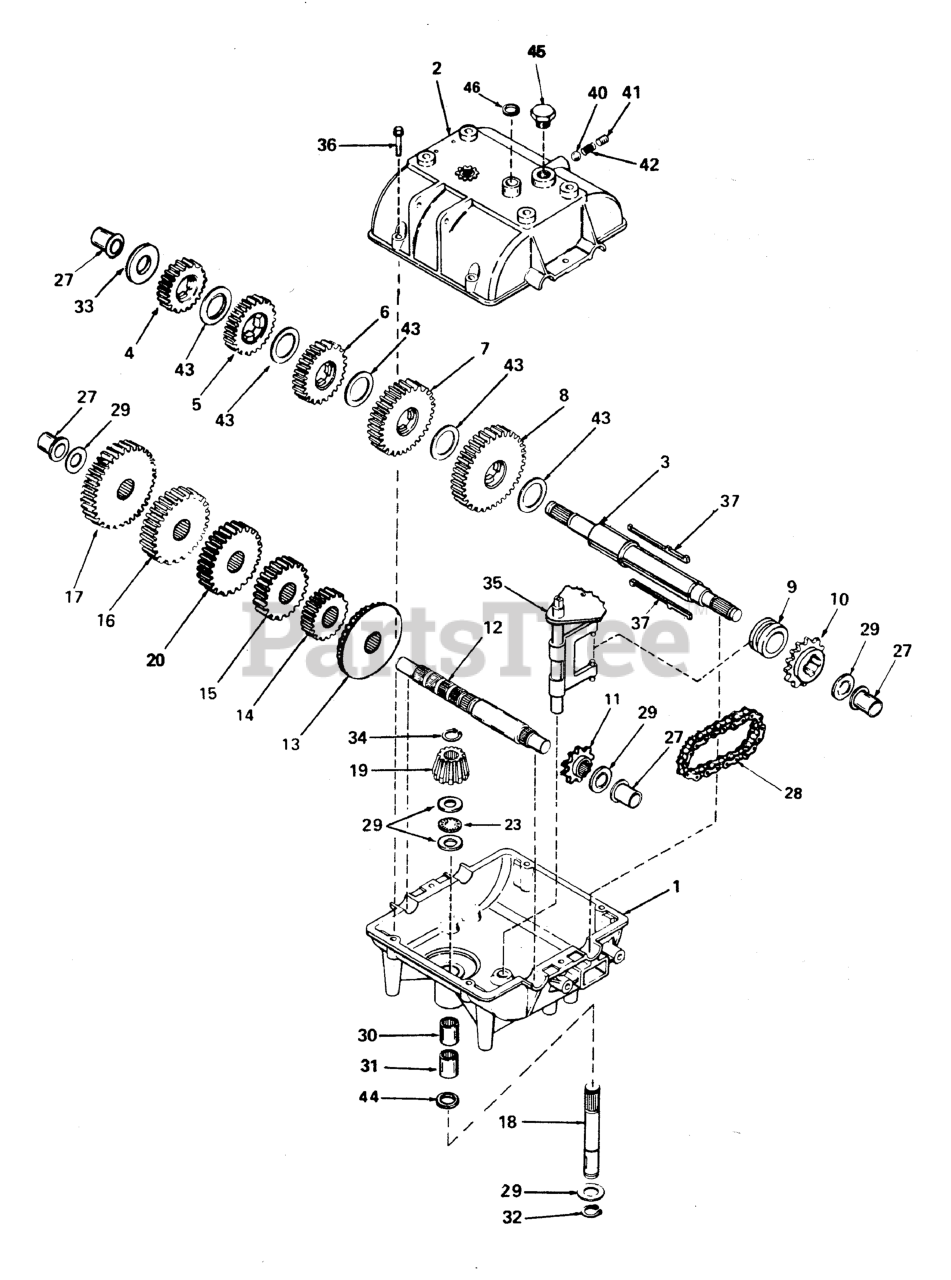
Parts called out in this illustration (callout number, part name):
1	Transmission Case
2	Transmission Cover
3	Output & Brake Shaft
4	Spur Gear (27 Tooth)
5	Spur Gear (30 Tooth)
6	Spur Gear (32 Tooth)
7	Spur Gear (35 Tooth)
8	Spur Gear (37 Tooth)
9	Shift Collar
10	Sprocket (18 Tooth)
11	Sprocket (9 Tooth)
12	Countershaft
13	Bevel Gear (42 Tooth)
14	Spur Gear (12 Tooth)
15	Spur Gear (15 Tooth)
16	Spur Gear (20 Tooth)
17	Spur Gear (23 Tooth)
18	Input Shaft
19	Input Bevel Pinion
20	Spur Gear (18 Tooth)
23	Thrust Bearing
27	Flanged Bushing
28	Chain, Roller (#41, 24 Links)
29	Thrust Washer
30	Needle Bearing
31	Needle Bearing
32	Retaining Ring
33	Thrust Washer
34	Retaining Ring
35	Shift Rod & Fork
36	Screw, Flanged Hex Head, Threadforming, 1/4-20 x 1-1/4"
40	Steel Ball, 5/16"
41	Set Screw, 3/8-16 x 3/8"
43	Thrust Washer
45	Threaded Plug
46	Square Cut Seal
